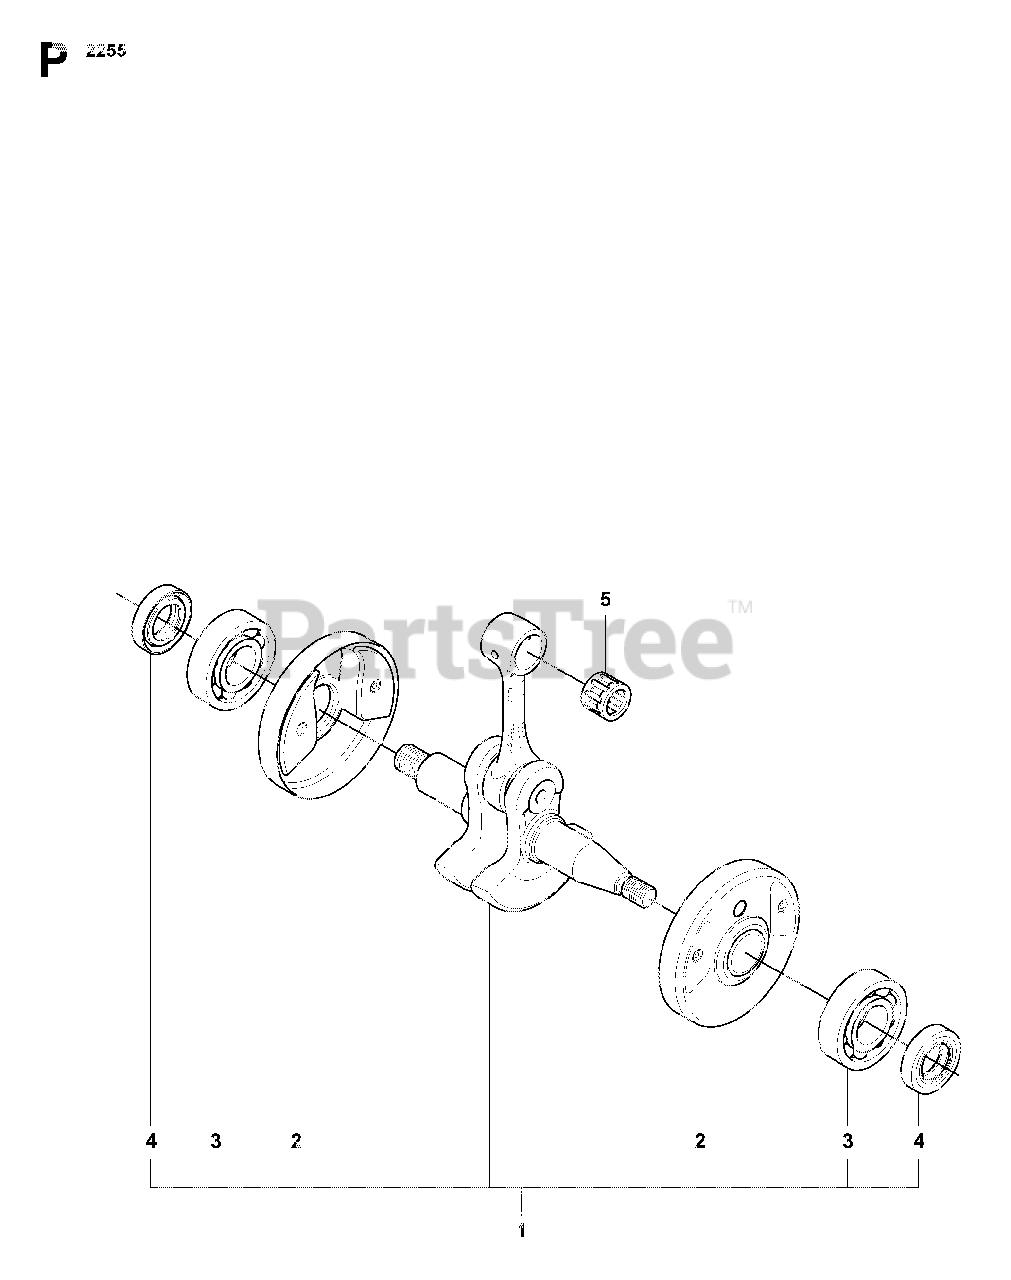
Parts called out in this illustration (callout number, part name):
1	CRANKSHAFT
3	BALL BEARING-6202-C3 SKF
4	SEALING RING
5	RP SUPPORT BUSHING
